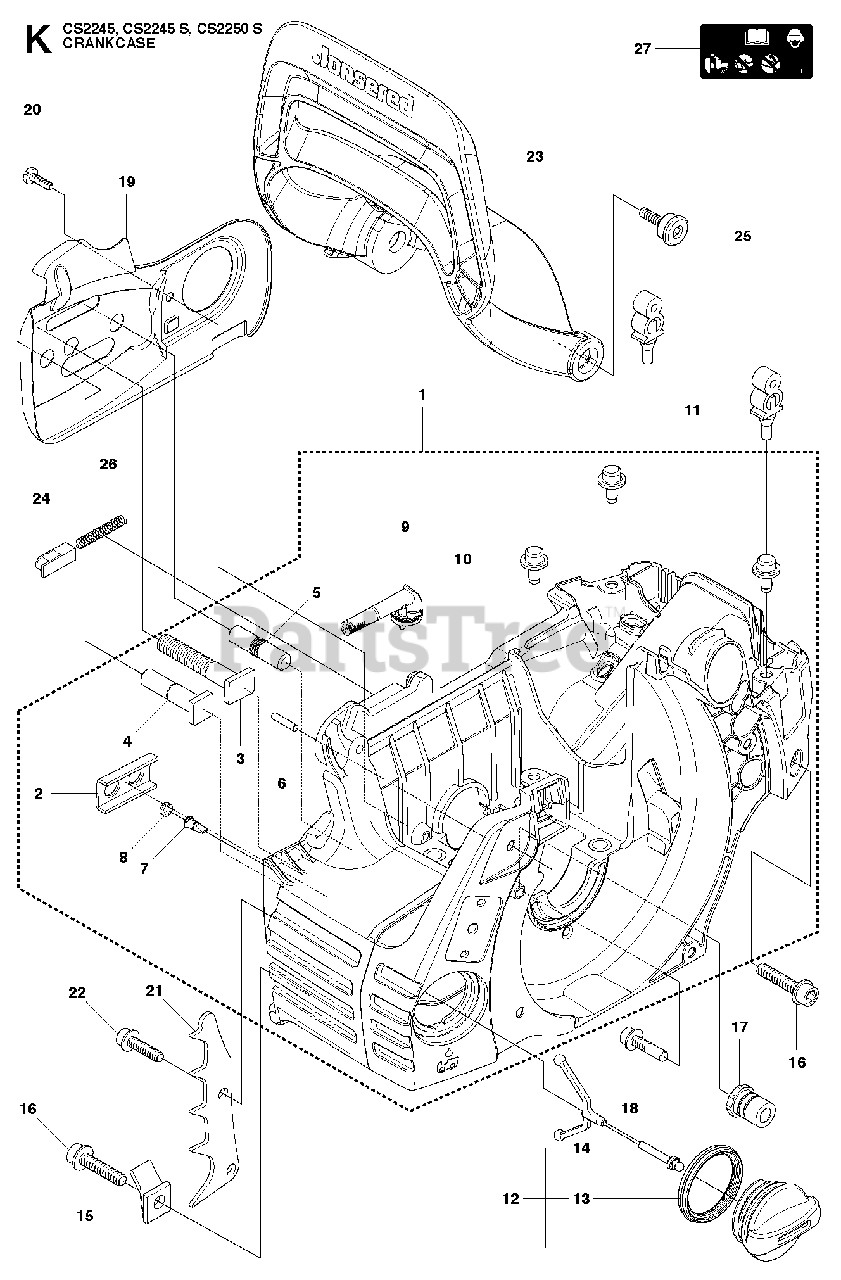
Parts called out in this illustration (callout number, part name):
1	CRANKCASE
2	STIFFENING PLATE
3	BAR BOLT
4	BAR BOLT (X2)
5	BAR BOLT
6	PIN
7	VALVE-CHECK (DUCKBILL)
8	PLUG
9	OIL SCREEN
10	GUIDE PEN
12	TANK CAP ASSY
13	SEALING
14	HOLDER
15	CHAIN CATCHER
16	SCREW IHSCFT
17	LATERAL SUPPORT
18	SCREW IHSCFT
19	CHAIN GUIDE PLATE
21	FELLING DOG
23	HAND GUARD
26	LOCK SPRING
